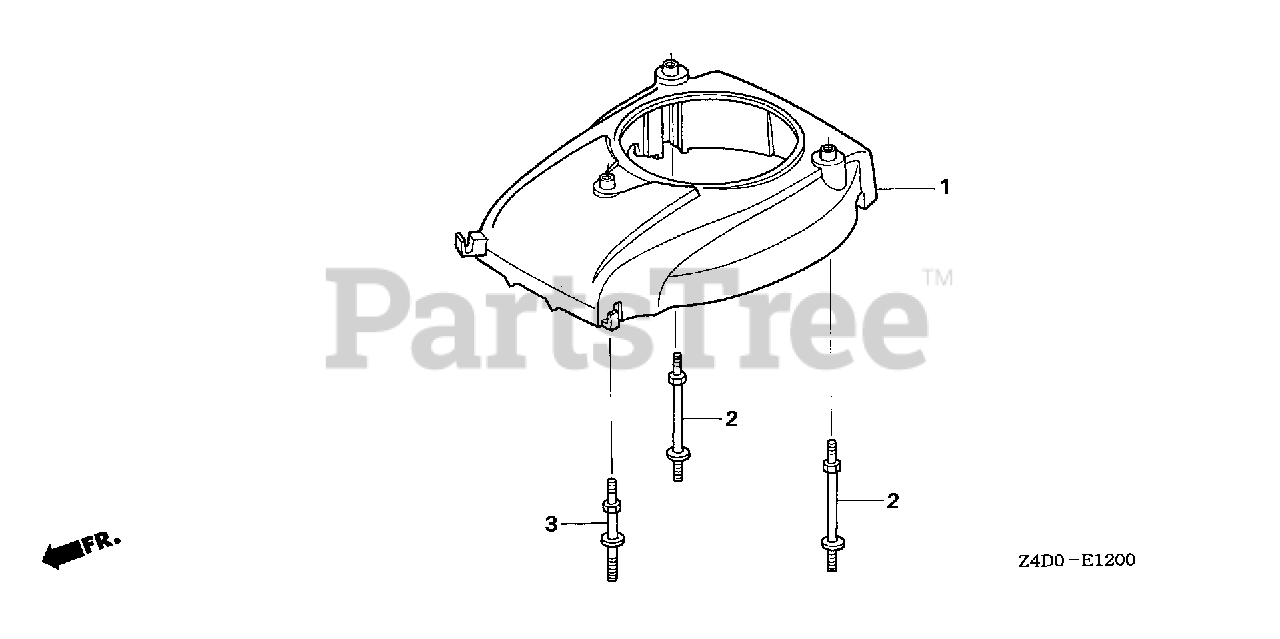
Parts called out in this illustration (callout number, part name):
1	COVER, FAN *R280* (POWER RED)
2	BOLT A, STUD
3	BOLT B, STUD
